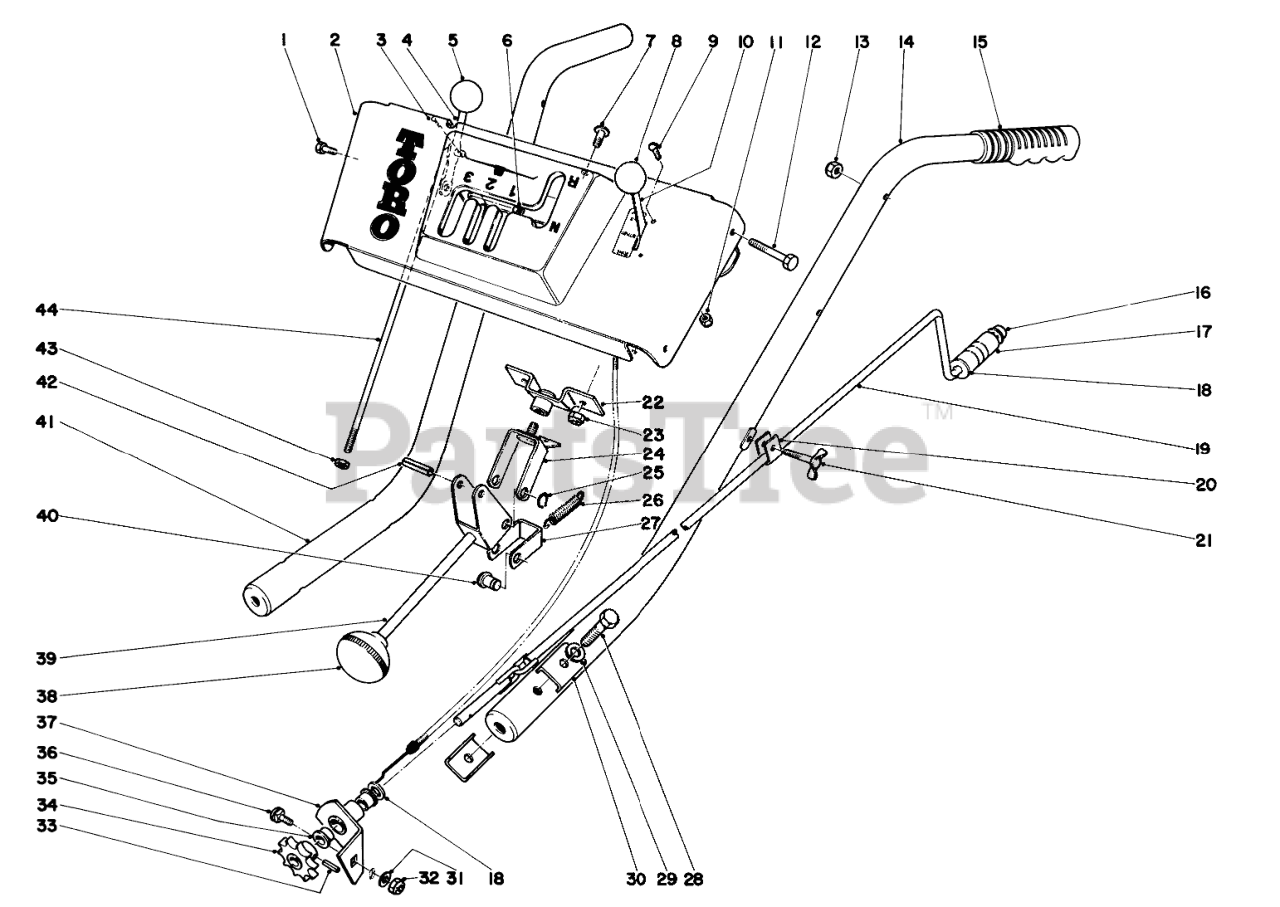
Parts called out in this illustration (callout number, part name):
1	SCREW-HH
2	Escutcheon Plate
3	PIN-COTTER
4	Control Wheel Clutch
5	BALL-GRIP
6	NUT-LOCK, NI
7	Screw, Machine
8	KNOB-CONTROL
9	SCREW-PPH
10	Control Throttle
11	NUT-LOCK, NI
12	SCREW-HH
13	NUT-LOCK, NI
14	Handle, Left
15	Grip Handle
16	Speed Nut
17	Chute Control Grip
18	WASHER-FLAT
19	Chute Control
20	Clamp, Chute Control
21	Thumb Screw
22	Swivel Block
23	NUT-LOCK, NI
24	Pivot Bracket
25	Ring-Snap
26	Spring Reverse
27	U-Clip
28	SCREW-HH
29	WASHER-LOCK
30	Stabilizer Handle
31	WASHER-FLAT
32	NUT-LOCK, NI
33	PIN-SPRING
34	Sprocket
35	BUSHING-FLANGE
36	SCREW-CARR
37	Chute Bracket (Incl. Ref. #35)
38	KNOB-LEVER
39	Control Rod
40	Pin Shift Lever
41	Handle, Right
42	PIN-ROLL
43	NUT-JAM
44	Upper Rod Wheel Clutch
